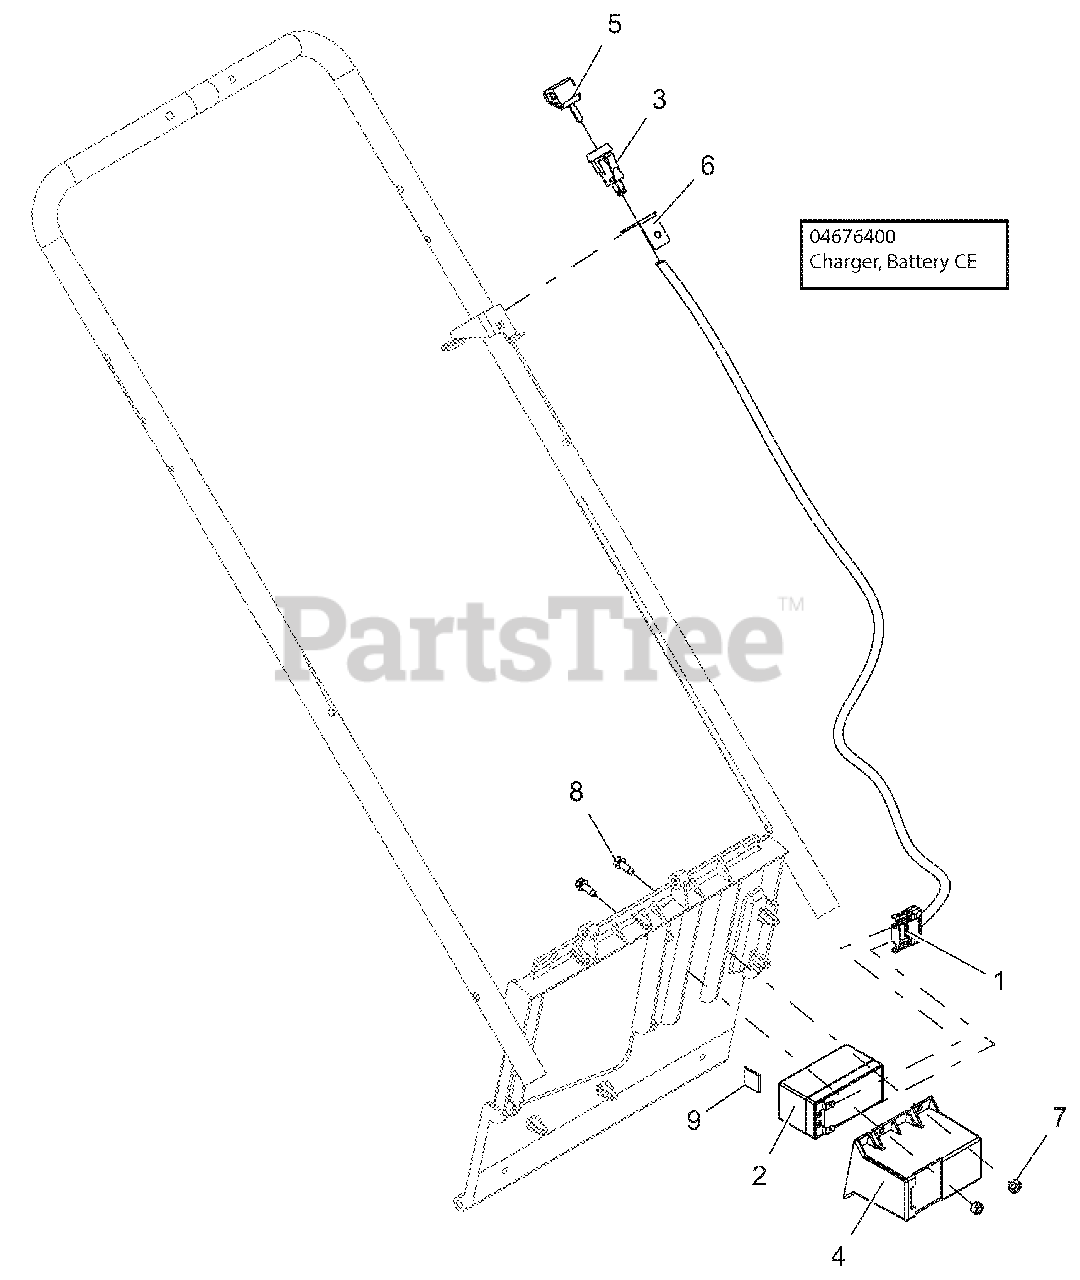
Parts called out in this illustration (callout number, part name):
1	HARNESS, ELEC START - SUBARU
2	BATTERY,LM(SEE BULLETIN B2117)
3	SWITCH, KEY
4	COVER, BATTERY
5	KEYS, IGNITION
6	BRKT, KEY SWITCH
7	@NUT-LK-CTR .25-20 YWZC
8	@SCR-TAP .25-20X.62 HWH TR YWZ
